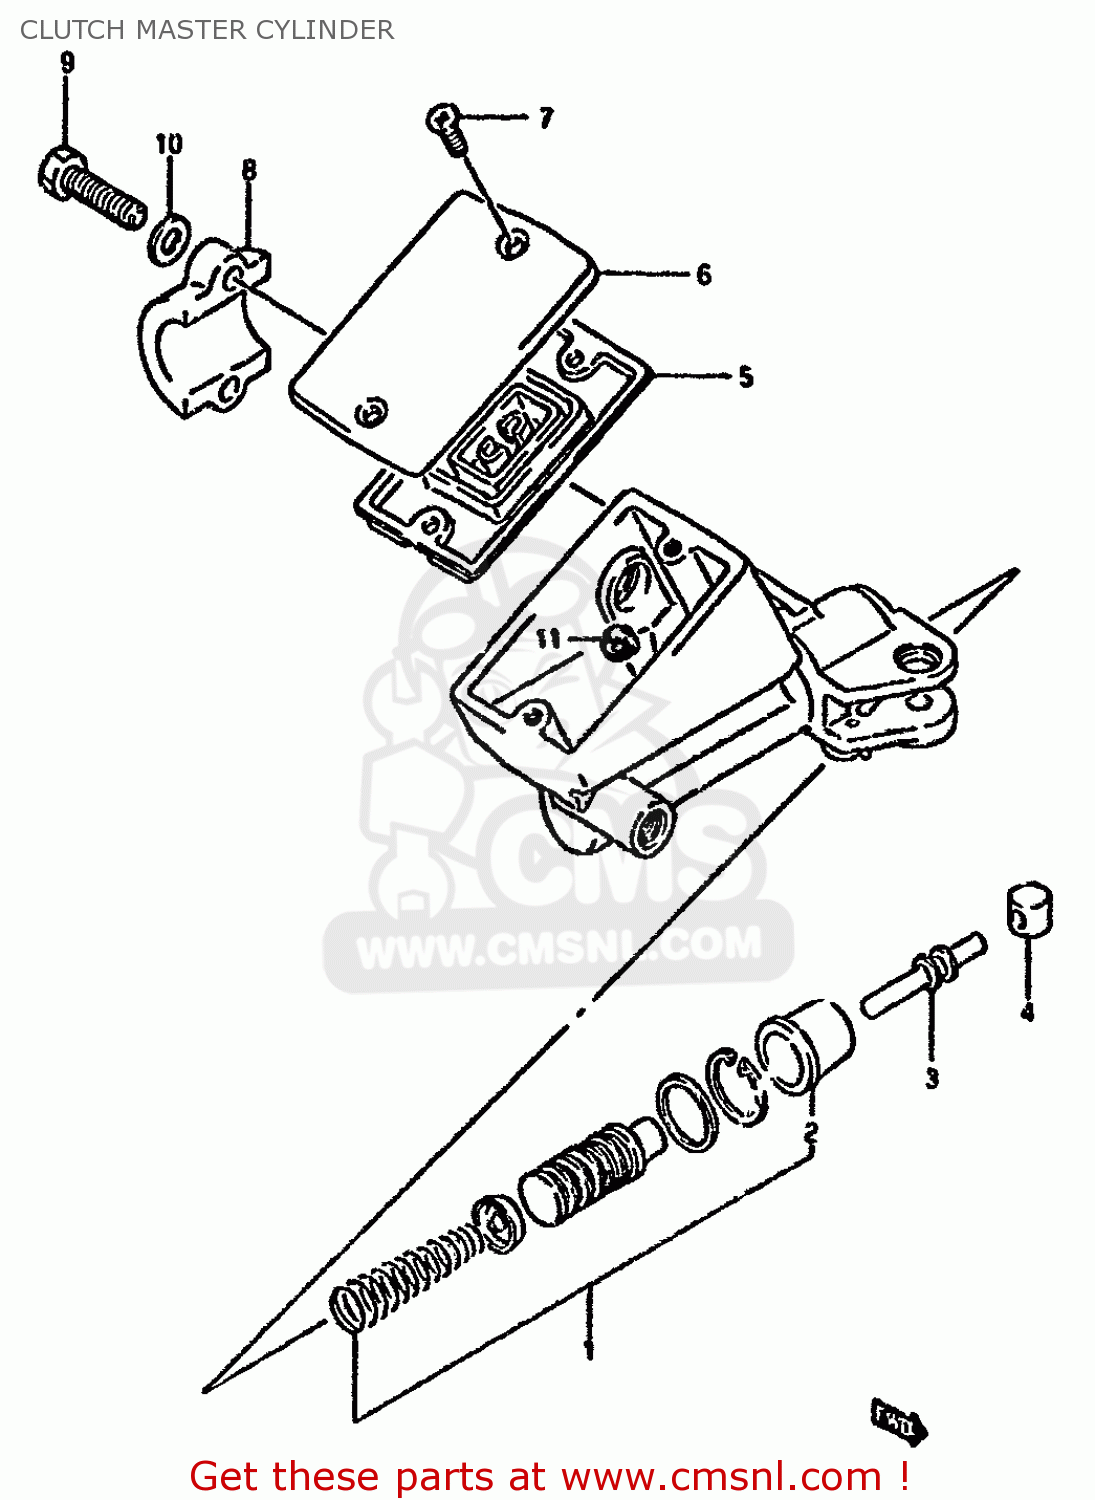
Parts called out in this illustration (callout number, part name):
1	PISTON & CUP SET
2	BOOT
3	ROD,PUSH
4	BUSH
5	6-1
6	CAP
7	SCREW
8	HOLDER
9	BOLT
10	WASHER
11	PROTECTOR
